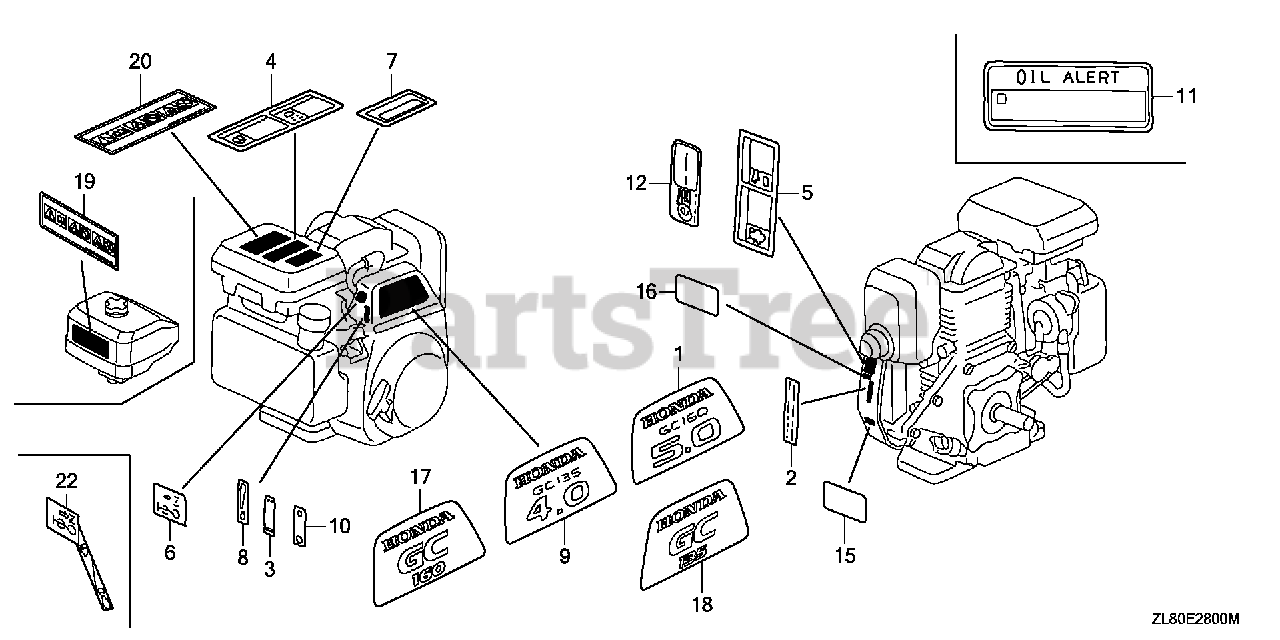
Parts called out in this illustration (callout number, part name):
1	EMBLEM (GC160)
6	MARK, CHOKE
8	MARK, THROTTLE INDICATION
15	LABEL, WARNING (NOT CERTIFIED FOR SALE)
